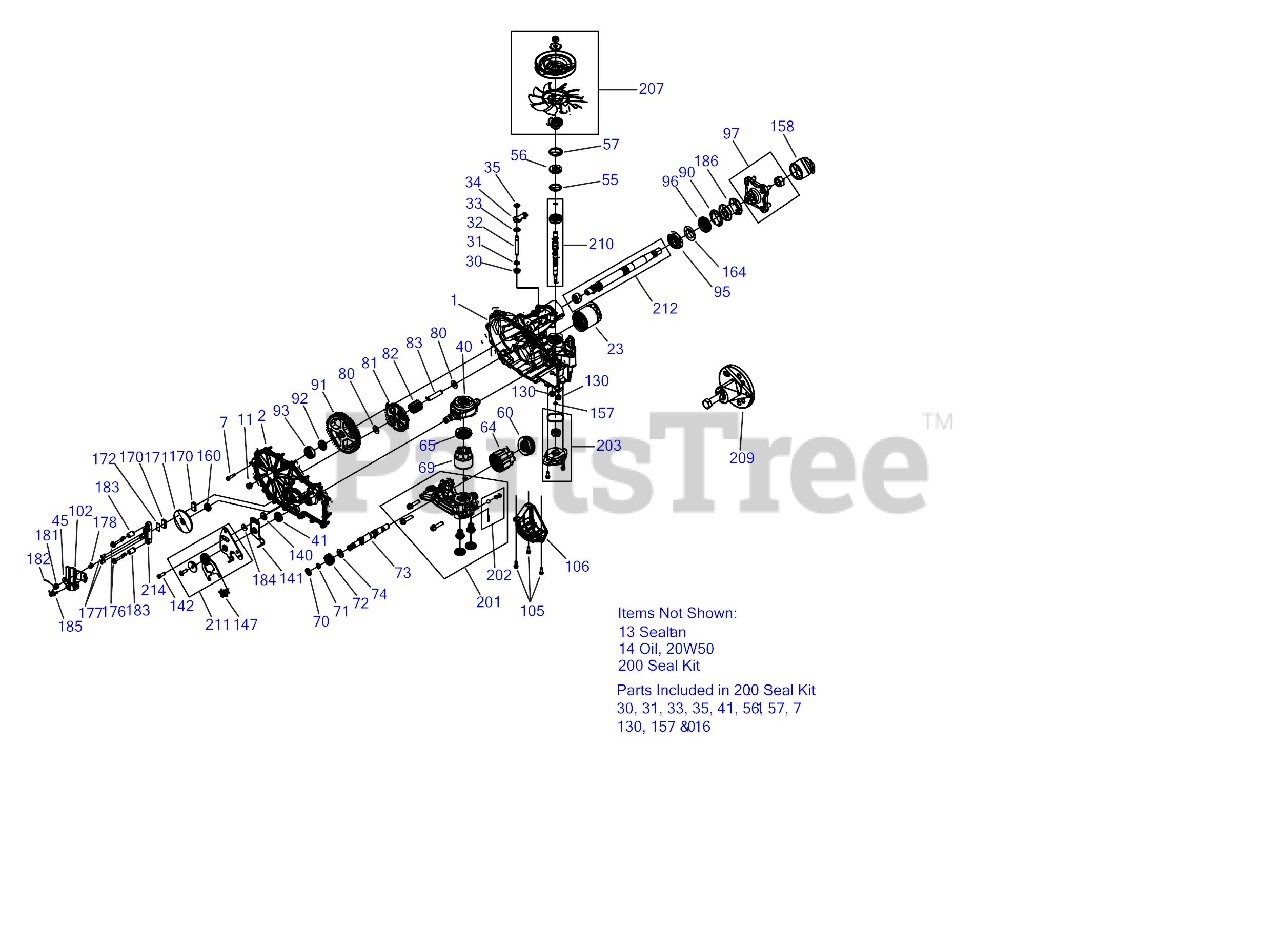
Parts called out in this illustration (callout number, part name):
1	Kit, Main Housing, LH Charge
2	Kit, Cover Side LH Control
7	Screw, Hex Washer
23	Filter, Spin-On 2.6 x 3.0
30	Seal, Lip, .375 x .75 x .25
31	Ring, Retaining .375 External
32	Rod, Bypass
33	Ring Retaining .750 Internal
34	Arm, Bypass
35	Ring, Ret .375 External
40	Trunnion, Swashplate
41	Seal, Lip 18 x 32 x 7
45	Washer, .34 x .88 x .06
55	Washer, 1.23 x 1.57 x .04
56	Seal, Lip 17 x 40 x 7
57	Ring Retaining Internal
60	Bearing, Thrust 35 x 62 x 18
64	Kit, 16cc Cylinder Block Assembly
65	Thrust Bearing, 30 x 52 x 13
69	Kit, Block, 7 Piston
70	Washer, .63 x 1.00 x .05
71	Ring, Reatining, Motor Shaft
72	Gear, 14T (Steel)
73	Shaft, Motor
74	Washer, .71 x 1.16 x .04
81	Gear, 45T
82	Gear, 11T (Steel)
83	Pin, Jackshaft
90	Ring, Retaining 2.25 Internal
91	Gear, 54T
92	Spacer, .750 x 1.00 x .257
93	Bearing, Ball 3/4 x 40mm x 12mm
95	Bearing, Ball 25.4 x 52 x 15
96	Seal, Lip, 1.0 x 2.06 x .38
97	Kit, Hub 4-Bolt
102	Arm, Brake
105	Screw, Hex Washer 1/4-20 x .75
106	Guard, Filter, LH
130	Tube, Charge Triple O-Ring
140	Spacer, .320 x 1.005 x .150
141	Arm, Neutral Right
142	SHCS, 5/16-24 x 7/8 (W/Patch)
147	Spring, Extension
157	Seal, Gerotor .281 x .420 x .160
158	Cap, Axle
160	Seal, Lip .625 x 1.00 x .250
164	Spacer, 1.355 x 2.035 x .021
170	Puck, Brake
171	Rotor, Brake
172	Puck, Plate
176	Screw .250-20 x 2.0 HFS Patch
177	Pin, Brake Actuating
178	Compression Spring
181	Nut, Castle 5/16-24
182	Pin, Cotter 3/32 x 3/4
184	Washer, .34 x .88 x .06
185	Spring, Brake Arm Bias
186	Tube, Axle 2.03
200	Kit. Seal, ZT-2800
201	Kit, Center Section LH Charge
202	Kit, Charge Relief
203	Kit, Charge
207	Kit, Fan Pulley
207	Fan Only
207	Pulley Hub
209	Kit, Hub Puller
210	Kit, Input Shaft
211	Kit, RTN Bidirectional
212	Kit, Shaft Axle
214	Kit, Brake Yoke
